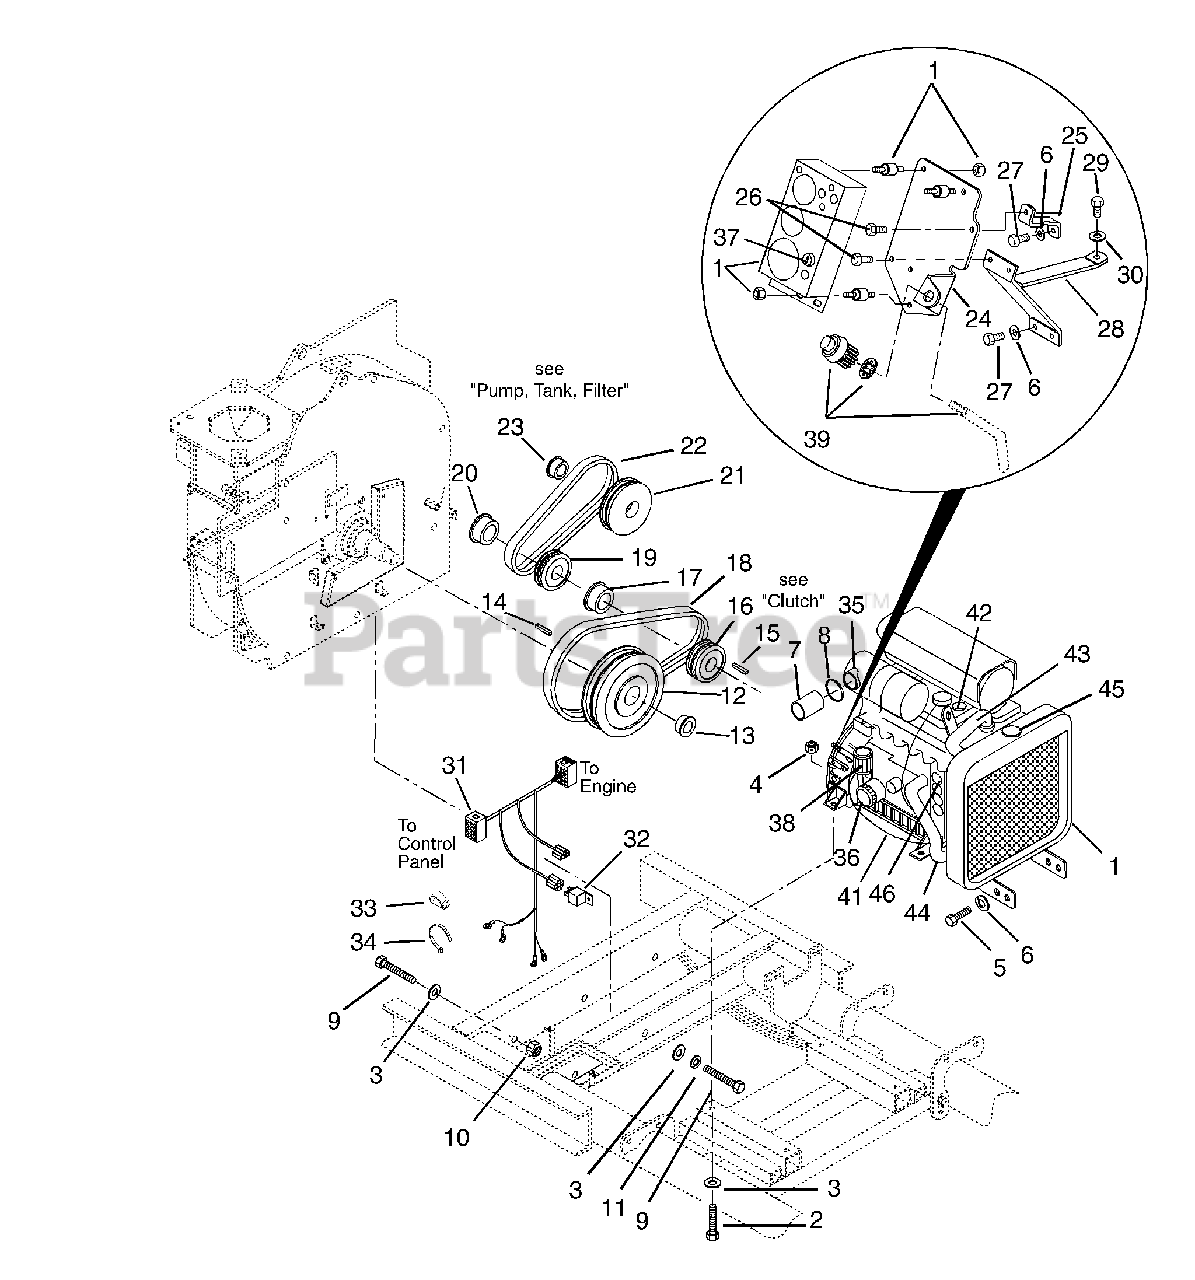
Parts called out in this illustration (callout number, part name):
1	Engine-Yanmar Diesel 44 HP 4TNE84-VM
2	Bolt-Hex .50-13 x 1.25 Grade 5
3	Washer-Flat-Steel .563 x 1.38 x 1.09
4	Nut-Locking-Center .50-13
5	Bolt-Hex M8 1.25 x 25 mm Grade 5
6	Washer-Locking .31 x .078
7	Hose-Air Intake 2.5 I.D. x 5.00
8	Clamp-Hose-Worm 2.3/3.2
9	Bolt-Hex .50-13 x 1.75 Grade 8
10	Nut-Locking-Cone .50-13 Grade C
11	Washer-Locking .50 x .125
12	Pulley 3V 10.60-2517
13	Bushing-Taperloc 2517-2
14	Key-Straight .50 x .50 x 1.75
15	Key-Square .375 x .375 x 1.25
16	Pulley 4G-3V 5.3
17	Bushing-SDS 1-7/16 O.D.
18	Belt - 4 x 3V475
19	Pulley 2G-3V 5.3
20	Bushing-SH 1-7/16 O.D.
21	Pulley 3V 6.90-1610
22	Belt-2 x 3V450
23	Bushing-Taperloc 1610-3/4
24	Mount-Instrument Panel
25	Bracket-Instrument Panel-Upper
26	Screw-Tapping .31-18 x .75 Hex Washer Head
27	Bolt-Hex M8 x 1.25 x 16 mm
28	Bracket-Instrument Panel-Lower w/Assembly
29	Bolt-Hex .38-16 x .75 Grade 5
30	Washer-Locking .38 x .094
31	Harness-Relay/Jumper Wiring
31	Harness, Wire- 944 Chipper
32	Relay
33	Clip-Wire
34	Tie Wrap
35	Air Filter Element, Primary
36	Oil Filter
37	Key, Ignition
37	Key Switch Assembly
38	Fuel Filter Element
38	Clamp, Fuel Line
38	Retainer, Fuel Filter Bowl
38	O-Ring, Fuel Filter
38	Nut, Fuel Filter Retaining
39	Throttle Cable
41	Plug, Oil Drain
41	Seal, Oil Plug
42	Oil Fill Cap
42	O-Ring, Oil Fill Cap
43	Hose, Upper Radiator
44	Hose, Lower Radiator
45	Cap, Radiator
46	Thermostat
